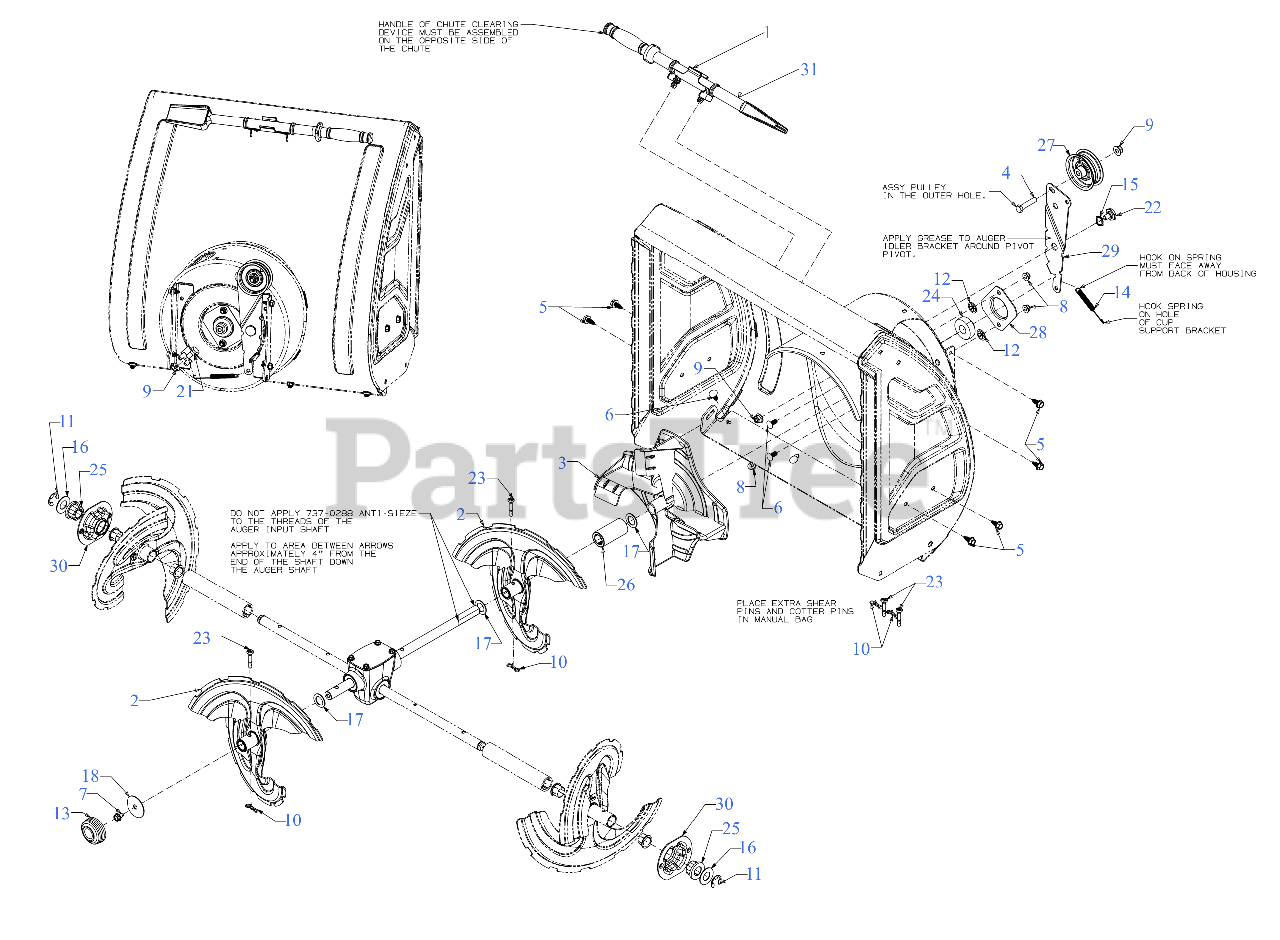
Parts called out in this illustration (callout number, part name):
1	CLEANOUT TOOL MOUNTING CLIP
4	HEX SCREW 3/8-16 x 1.75 GR5
5	SCREW 5/16-18 x .750
6	CARRIAGE BOLT 5/16-18 x .75
7	SCREW 5/16-18 x .500
8	FLANGE LOCK NUT 5/16-18
10	BOW TIE COTTER PIN 1/4-5/16
11	E-RING
12	PUSH NUT
13	CASTER AXLE CAP
14	EXTENSION SPRING .38 OD x 4.59
15	WAVE WASHER .660 ID X.88 OD x .010
16	FLAT WASHER .760ID X1.49OD x .06
17	FLAT WASHER .793 ID X1.240X.06
18	HUB CAP WASHER .406 x 1.92 x .060
21	SHOULDER SCREW .498 DIA x .340
22	SHOULDER SCREW .625 DIA x .163
23	SHEAR PIN (.25 x 1.50)
24	BEARING W/OUT COLLAR
25	FLANGE BEARING
27	FLAT IDLER PULLEY 2.75 OD
28	BEARING HOUSIN 1.85 ID
29	AUGER IDLER BRACKET
31	CLEANOUT TOOL
